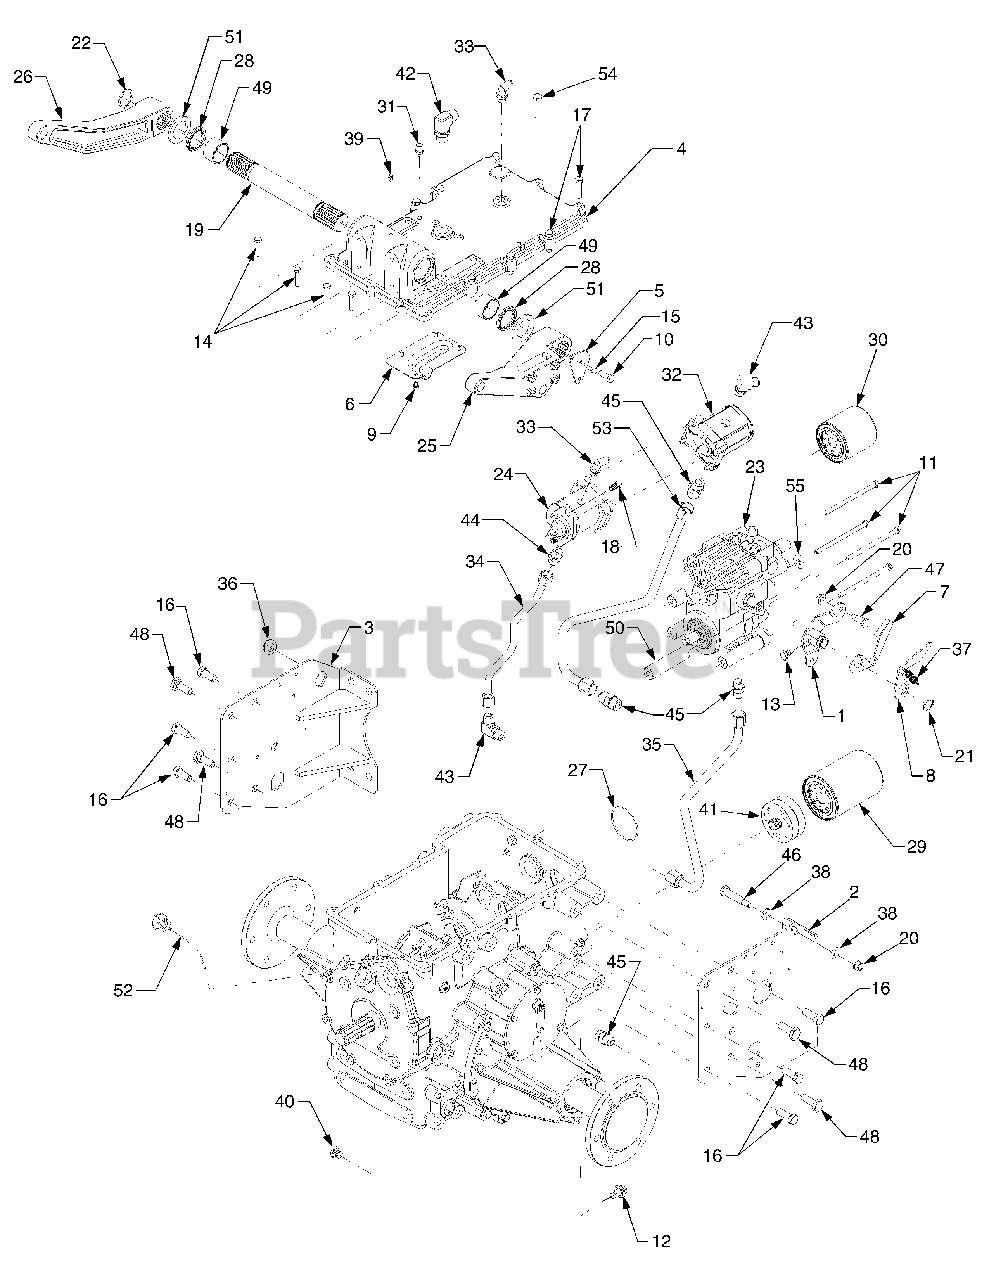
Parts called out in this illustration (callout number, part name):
1	Arm, Hydro Control
2	Bracket, Transmission Mtg. RH
4	Cover, Transmission Housing
5	Plate, Feedback
6	Baffle, Oil
7	Arm, Neutral RH
8	Arm, Neutral LH
9	Screw, Hex Cap, 1/4-20 x .375 GR5
10	Screw, Hex Cap Lock, 3.8-24 x 1.0 GR5
11	Screw, Hex Cap, 5/16-18 x 5.25 GR5
12	Screw, Plug, M14 x 1.5 x .827
13	Screw, Hex Special Set, 5/16-18 x .625
14	Screw, Hex Cap, 3/8-16 x 1.25 GR5
15	Screw, Hex Cap, 1/4-20 x .5 GR5
16	Screw, Hex Cap, 1/2-13 x 1.25 GR5
17	Screw, Hex Cap Lock, 3/8-16 x 1.5 GR5
18	Screw, Low Hd. Cap, 3/8-16 x .75
19	Shaft, Rock
20	Nut, Hex Flange Lock, 3/8-16
21	Ring, Retaining
22	Ring, Retaining
23	Pump, Hydrostatic Transmission
24	Pump, Auxiliary Hydraulic
25	Arm, Upper Hitch RH
26	Arm, Upper Hitch LH
27	O-Ring, 2.987 ID x .103 Dia
28	Seal, Oil, 1.5 x 2.0 x .25
29	Filter, Oil
30	Filter, Oil
31	Breather, Transmission
32	Auxiliary Hydraulic Pump
33	Fitting, 90 degree
34	Tube, Auxiliary Pump Suction ...
35	Tube, Hydro Suction
37	Spring, Extension
38	Washer, Flat, .406 x 1.0 x .105
39	Fitting, Grease
40	Plug, Fitting
41	Housing Ass’y, Reverse Flow
42	Fitting, 90 degree
43	Fitting, 90 degree
44	Fitting, Straight
45	Fitting, Straight
46	Screw, Shoulder, .498 Dia x 1.45
47	Screw, Shoulder, .50 Dia x .685
48	Screw, Shoulder, .625 x .18: 1/2-13
49	Bearing, Sleeve, 1.52 x 1.75 x 1.0
50	Spacer, .40 x 1.0 x 3.9
51	Spacer, 1.52 x 2.25 x .188
53	Tube, Tandem Pump Suction
54	Screw, Hex Cap, 3/8-16 x 1.25 GR5
55	Washer, Flat, .349 x 1.12 x .125 Hrd
